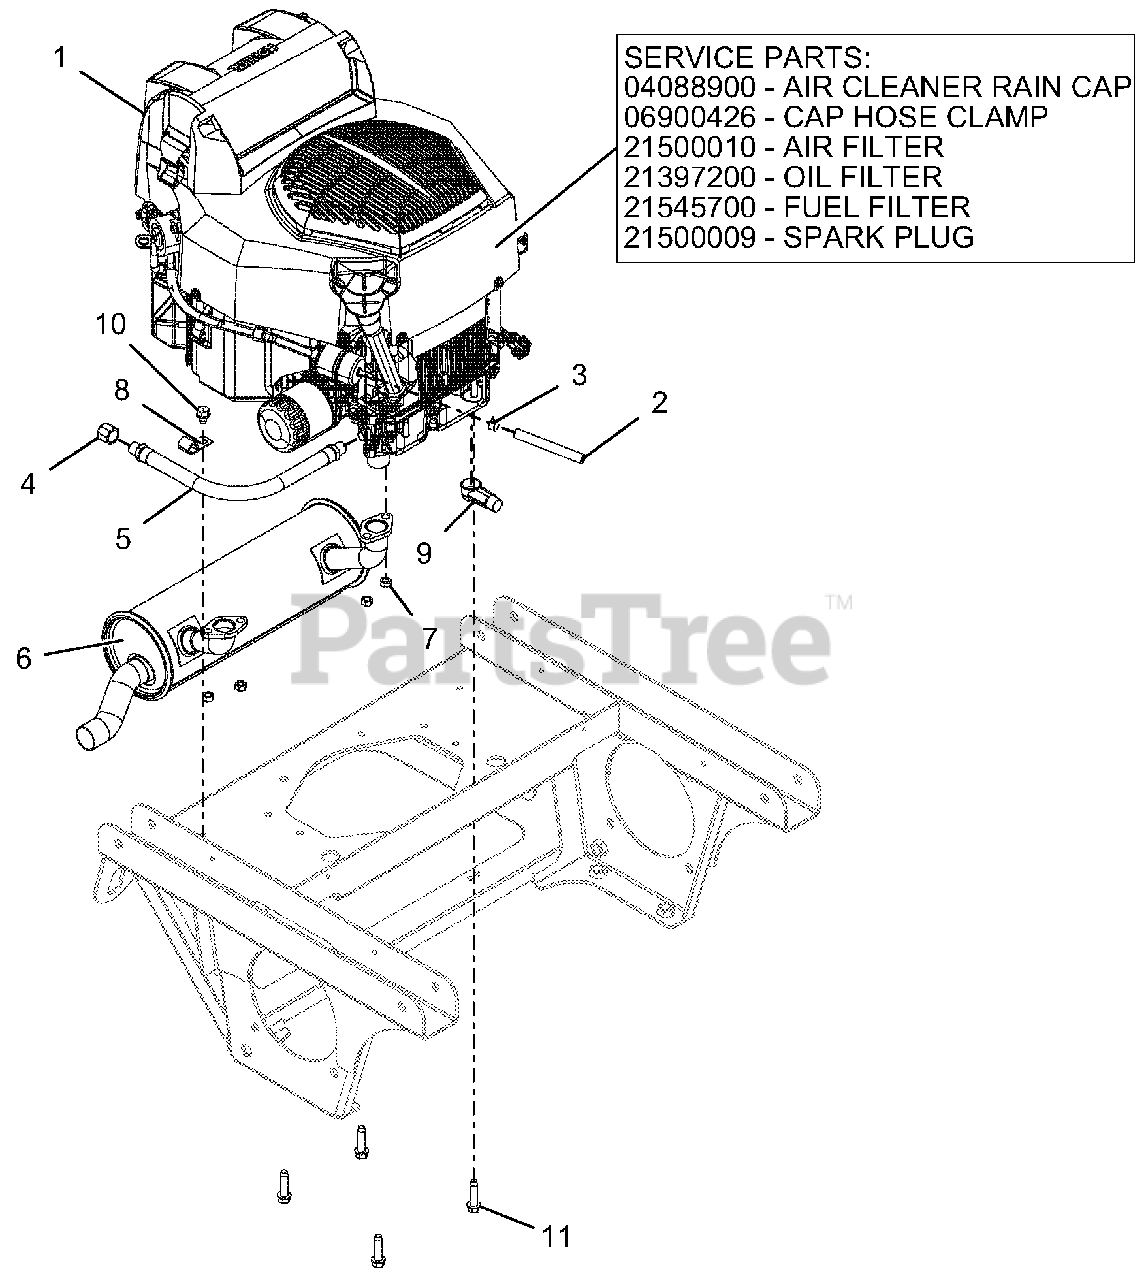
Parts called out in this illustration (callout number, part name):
1	FILTER, OIL - KOH CV20
1	CAP, KAW 11065-7025
1	CLAMP, HOSE #36 SS 1.813-2.75
1	AIR CLEANER, KOHLER CONFIDANT
1	FILTER-FUEL KOHLER COURAGE PRO
1	PLUG, SPARK KOHLER
1	ENGINE, KOHLER ZT740 CONFIDANT
2	HOSE, .25 LOW-PERM BULK GAS
3	CLAMP, FUEL LINE
4	PIPE CAP 3/8 NPT FEMALE
5	HOSE,HYD .38-14-0K M6N0-M6N0
6	MUFFLER, ZT730/ZT740
7	NUT-LK-TOP M8-1.25 YWZC
9	BOOT, .65ID POS
10	@SCR-TAP .38-16X.50 HWH TR YWZ
11	@SCR-TAP .38-16X1.50 HWH TR YZ
